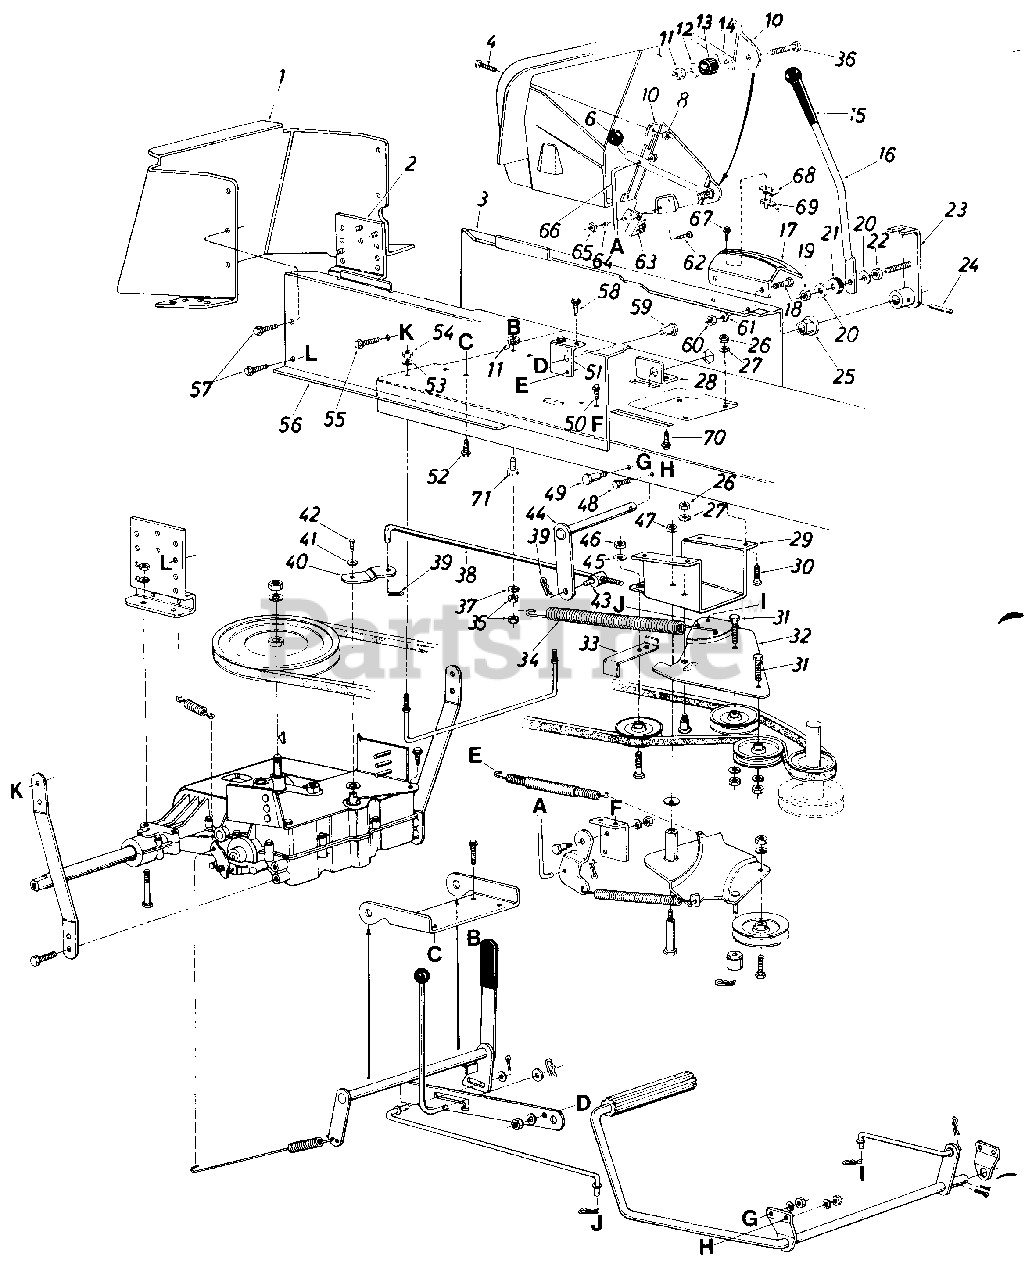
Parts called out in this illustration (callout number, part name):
1	Hitch Plate
2	Transaxle Support Bracket
3	Side Panel Upper Frame L.H.
4	Truss. Mach. Scr. 1/4-20 x .50" Lg.*
6	Ball Knob
8	Hex Sems Nut 1/4-20 Thd*
10	Deck Clutch Control Brkt.
11	Hex Nut 1/4-20 Thd.*
12	Fl-Wash. .281" I.D. x .734" O.D. x .063 Thk.
13	Rubber Wash. .330" I.D. x .87" O.D. x .32 Thk.
14	Blade Clutch Lever
16	Shift Lever
17	Shift Bracket
18	Hex Bolt 5/16-18 x .62" Lg.*
19	Hex Cent. L-Nut 5/16-18 Thd.
20	Fl-Wash. .344" I.D. x .875" O.D. x .063 Thk.
21	RubberWash. .330" I.D. x .87" O.D. x .32 Thk.
22	Hex Nut 5/16-18 Thd.
23	Handle Mount Brkt. Ass'y.
24	Spring Pin Spiral 1/4" Dia. x 1.5" Lg.
25	Plastic Hex Bearing .625" I.D.
26	Hex Nut 5/16-18 Thd.
27	L-Wash. 5/16" I.D.
28	Speed Control Shaft Brkt.
29	Transaxle Clutch Support Brkt.
30	Hex Bolt 5/16-18 x 2.50" Lg.
31	Hex Bolt 3/8-16 x 1.25" Lg.
32	Idler Bracket Ass'y.
35	Hex Nut 5/16-18 Thd.
36	Hex Bolt 1/4-20 x 1.25" Lg.
37	L-Wash. 5/16" I.D.
38	Shift Link
39	Hairpin Cotter 3/8"
40	Shifter Bracket
41	Belleville Wash. .25" I.D. x .375" O.D.
42	Hex Bolt 1/4-28 x .62" Lg.
43	Pivot Bushing
44	Speed Control Shaft Ass'y.
45	Fl-Wash. .385" I.D. x .87" O.D. x .060 Thk.
46	Hex Cent. L-Nut 3/8-24 Thd.
47	Hex Cent. L-Nut 3/8-16 Thd.
48	Hex Bolt 3/8-16 x .62" Lg.
49	Shoulder Bolt .500" Dia. x .345" Lg. (3/8-16)
50	Hex Thd. Rolling Scr. 1/4-20 x.50" Lg.
51	Parking Brake Cam Mtg. Brkt.
52	Hex Thd. Rolling Scr. 1/4-20 x.50" Lg.
53	L-Wash. 1/4" I.D.
54	Hex Nut 1/4-20 Thd.*
55	Hex Wash. Hd. TT-Tap Scr. 3/8-16 x .5" Lg.
56	Side Panel Upper Frame-R.H.
57	Hex Thd. Rolling Scr. 5/16-24 x .50" Lg.
58	Hex Thd. Rolling Scr. 1/4-20 x.50" Lg.
59	Shoulder Bolt .435" Dia. x .160 (5/16-18)
60	Hex Nut 5/16-18 Thd.
61	L-Wash. 5/16" I.D.*
62	Truss Mach. Scr. #10-24 x .50" Lg.*
63	Safety Switch
64	Ext. L-Wash. #10 Scr.
65	Hex Nut #10-24 Thd.
66	Deck Control Rod
67	Hex Wash. Hd. Scr. #8 x .50" Lg.
68	Insulator Nut Plate
69	Spring Switch
70	Hex Wash. Hd. AB-Tap Scr. 5/16 x .75" Lg.
71	Hex Wash. Hd. TT-Tap Scr. 1/4 x 1.5" Lg.
